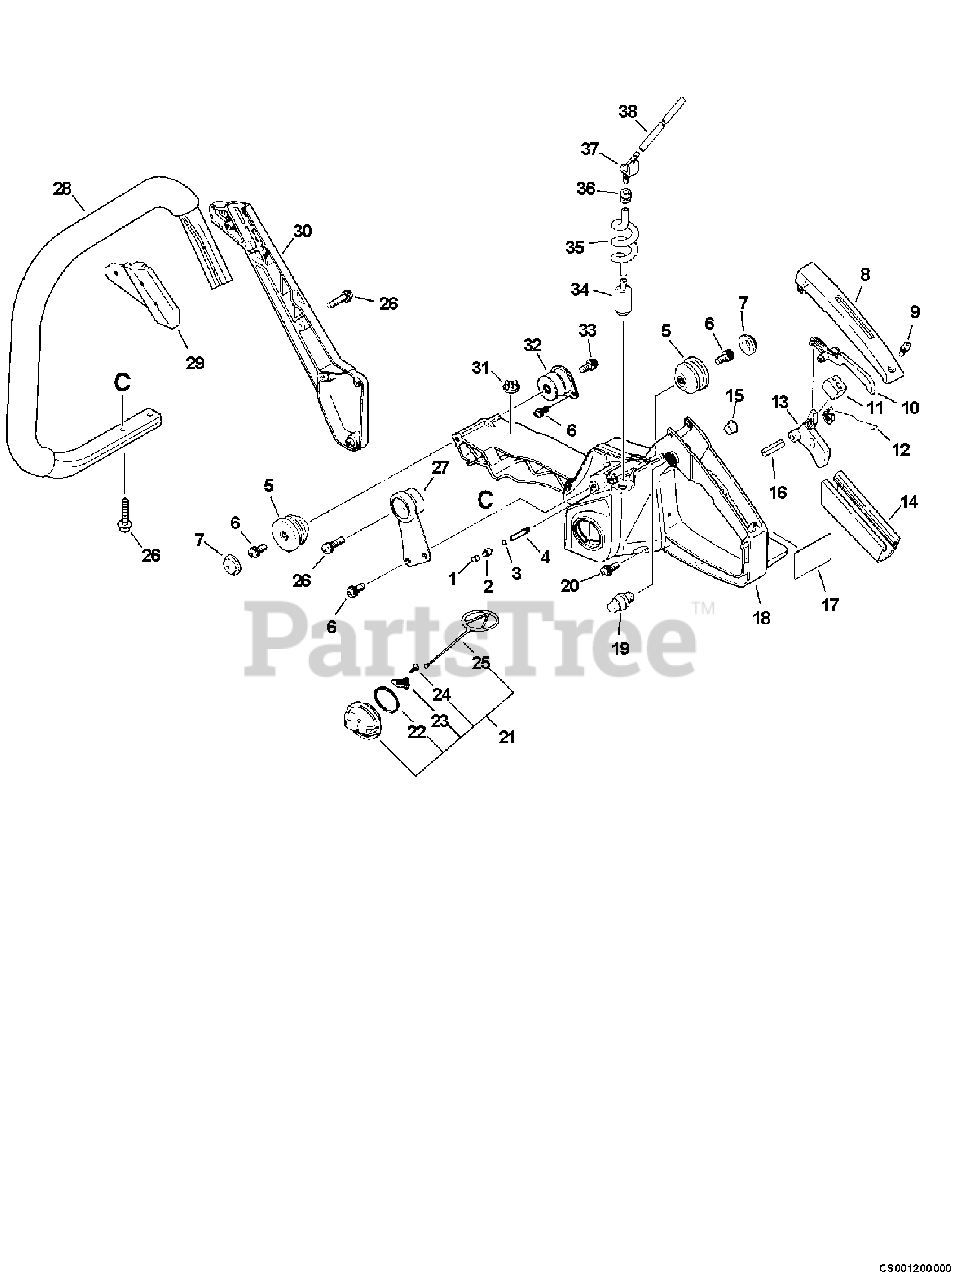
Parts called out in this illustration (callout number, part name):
1	VENT, FUEL TANK
2	COVER, VENT
3	CLIP - 5.5
4	PIPE - 3X5X55 -- BLACK
6	SCREW - 5X14
7	CAP, CUSHION
8	COVER, HANDLE
9	SCREW - 4X14
10	LEVER, TRIGGER LOCKOUT
12	SPRING, TRIGGER
13	TRIGGER, THROTTLE
14	GRIP, HANDLE
16	PIN - SPRING -- 5X25
17	LABEL - CAUTION
18	HANDLE - REAR
19	LATCH, THROTTLE
20	SCREW - 4X14
21	CAP ASSY
22	O-RING - 29
23	RETAINER
24	SCREW - 3X8
25	CONNECTOR, CAP
26	SCREW - 5X20
28	HANDLE - FRONT
29	BRACKET, HANDLE
30	BRACKET, HANDLE
33	SCREW - 4X10
34	FILTER, FUEL
35	PIPE - BLACK
36	GROMMET
37	CONNECTOR, PIPE
38	PIPE - 3X6X120 -- BLACK
